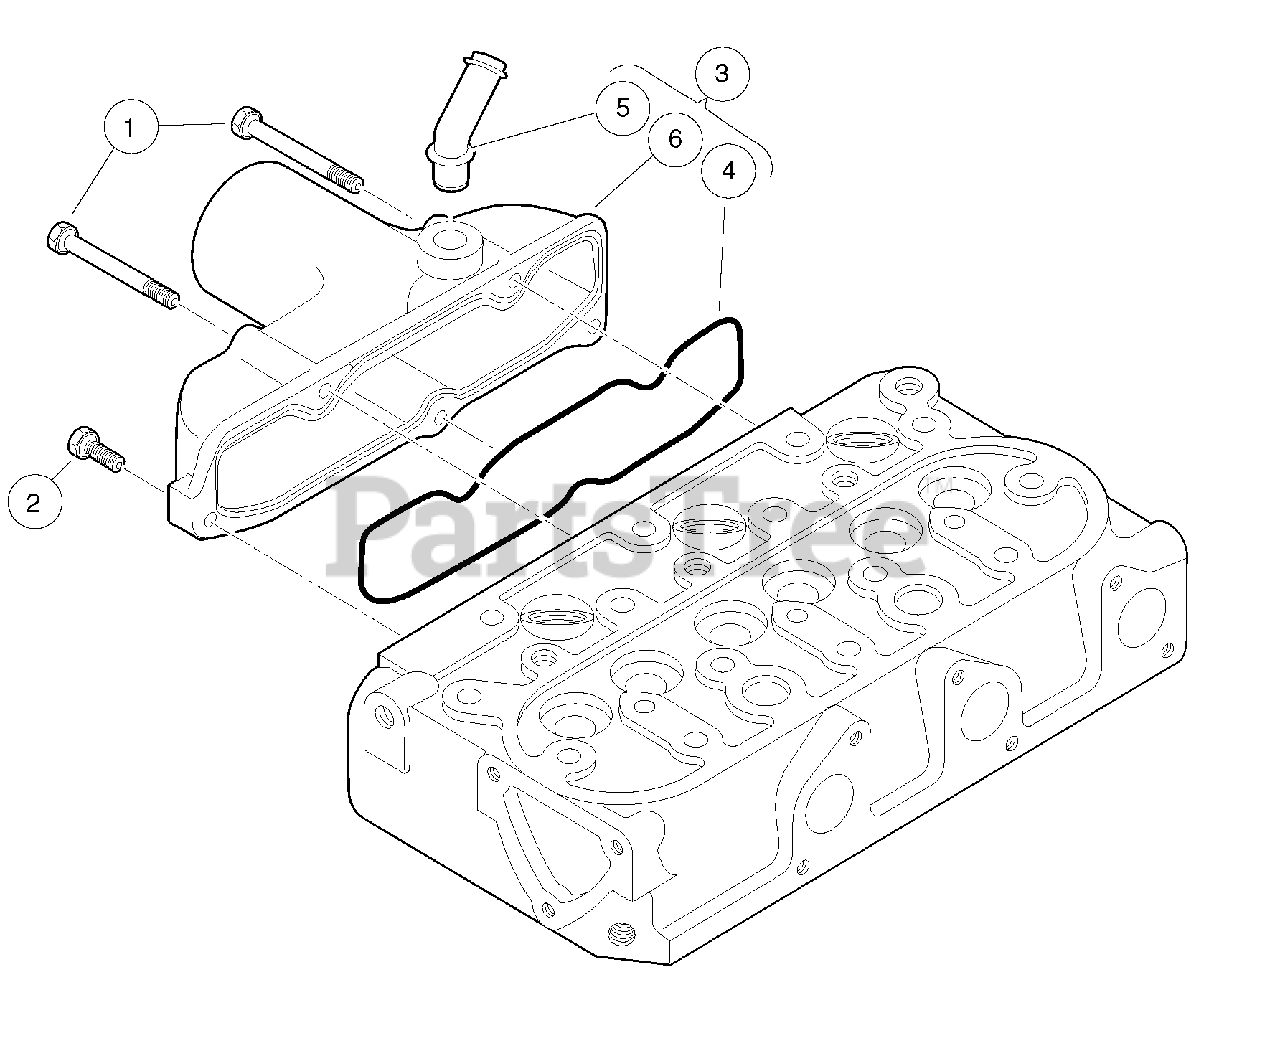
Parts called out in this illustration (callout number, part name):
1	Bolt, M6 X 1 X 45
2	Bolt, D722 Intake Manfld Lower
3	Assembly, Intake Manifold
4	Gasket, Intake Manifold
5	Pipe, Breather
6	Manifold, Intake
